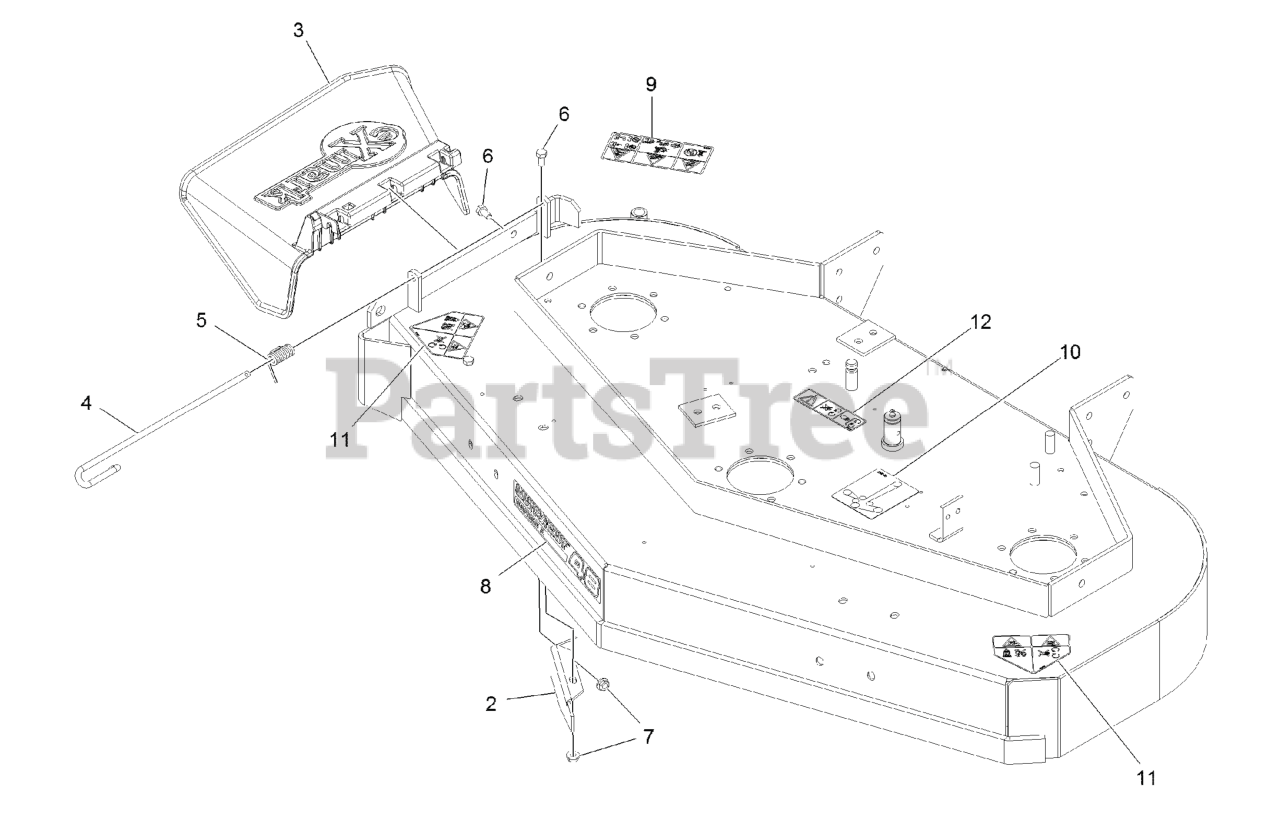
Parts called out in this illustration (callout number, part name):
2	BAFFLE-DOGLEG
3	CHUTE DEFLECTOR XRK M056
4	PIN-CHUTE
5	SPRING, TORSION
6	SCREW-HH
8	DECAL-ULTRACUT 48 SERIES
9	DECAL-WARNING, BAGGER
10	DECAL-ROUTING, BELT
11	DECAL-DANGER
12	DECAL-COVER, MISSING
